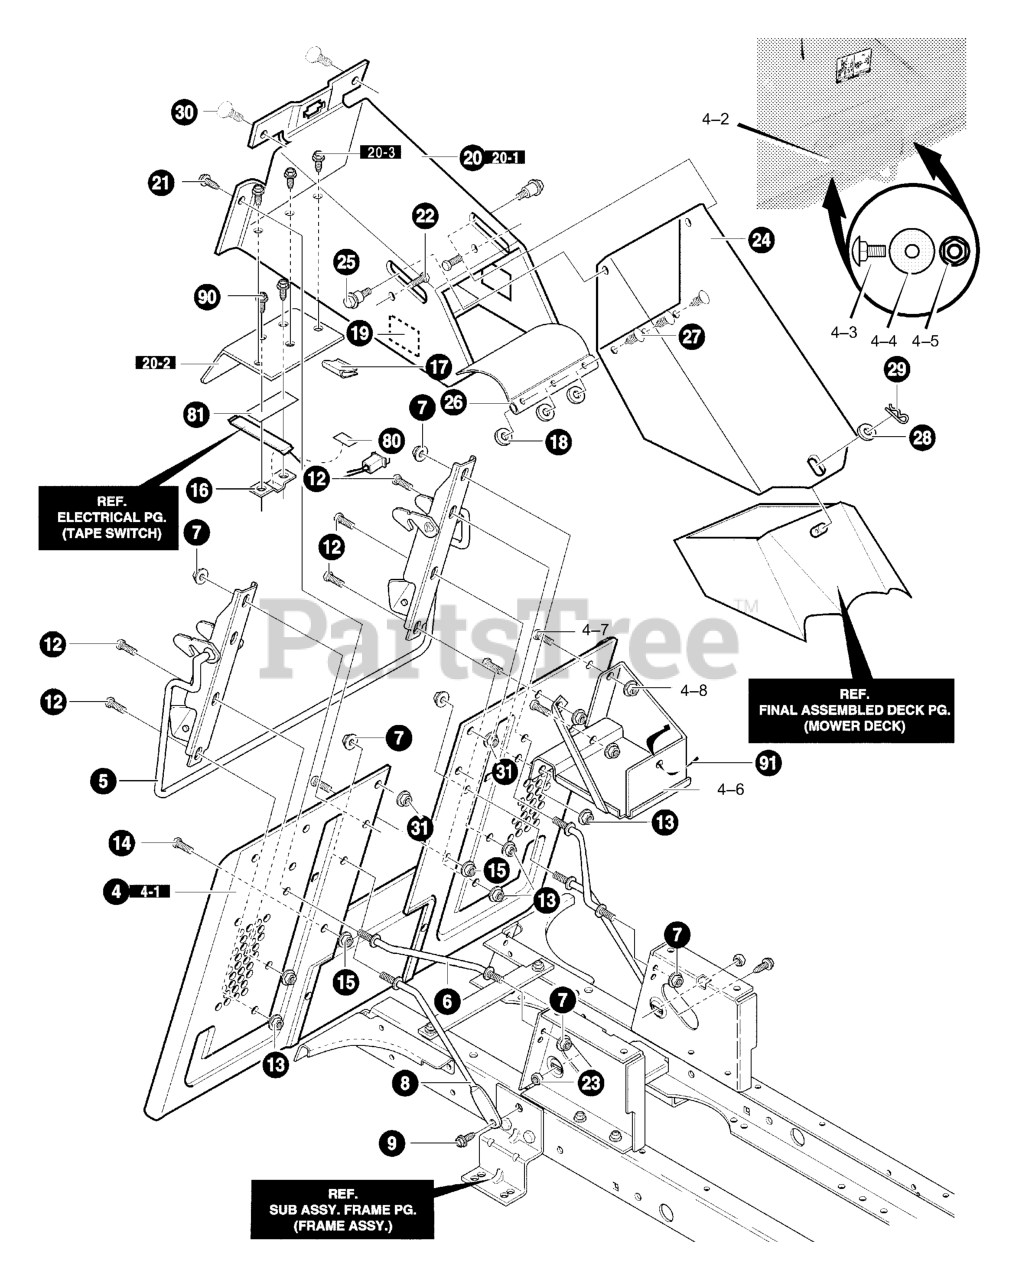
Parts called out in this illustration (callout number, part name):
4	ASSY, BACK PLATE/BATTERY
4-1	ASM. BACKPLATE, ONE PIECE
4-2	HITCH, FLAT BACK PLATE
4-3	BOLT, CARRIAGE
4-4	NUT, HEX
4-5	WASHER, FLAT
4-6	BATTERY TRAY ASM.
4-7	SCREW, 5/16-18 x 0.50 HHC
4-8	NUT, 5/16-18 HEXWDFLLK WHIZ
5	WELDMENT - LATCH LEVER
6	ROD, BRACE
7	NUT, 3/8-16 HWDFL WHIZ-LOCK
8	ROD, BRACE
9	SCREW, 5/16-18 x 0.75 HHWATAP
12	SCREW 5/16-18X.75 WDFLW
13	NUT, 5/16-18 HEXWDFLLK WHIZ
14	SCREW 5/16-18X.75 HHWATAP
15	NUT, 5/16-18 HEXWDFLLK WHIZ
16	BRACKET, FLEX SWITCH MOUNTING
17	WIRE CLIP, ADHESIVE
18	FLATWASHER, .250X.56X.047
19	PAD, ADHESIVE 1.00X1.50X.12
20	ASM., T/A SHIELD & UPPER CHUTE
20-1	CHUTE WELD ASM. UPPER
20-2	SHIELD, TRANSAXLE
20-3	SCREW, 1/4-20X.63 HHWATAP
21	SCREW, 5/16-18 x.75 HHC
22	BOLT, 5/16-18X.75 CARR
23	NUT, 5/16-18 HEXWDFLLK WHIZ
24	MIDDLE CHUTE ASSY
25	BOLT, SHOULDER, 3/8-16
26	FLAP, CHUTE
27	FASTENER, RATCHET
28	FLATWASHER
29	PIN, HAIR .38DIAX1.64LG
30	BOLT, 5/16-18X.75 CARR.
31	NUT, 5/16-18 HEXWDFLLK WHIZ
80	TAPE, DOUBLE SIDED FOAM 3/4" WD
81	TAPE, DOUBLE SIDED FOAM 3/4" WD
90	SCREW, 1/4-20X.63 HHWATAP
91	CABLE TIE
